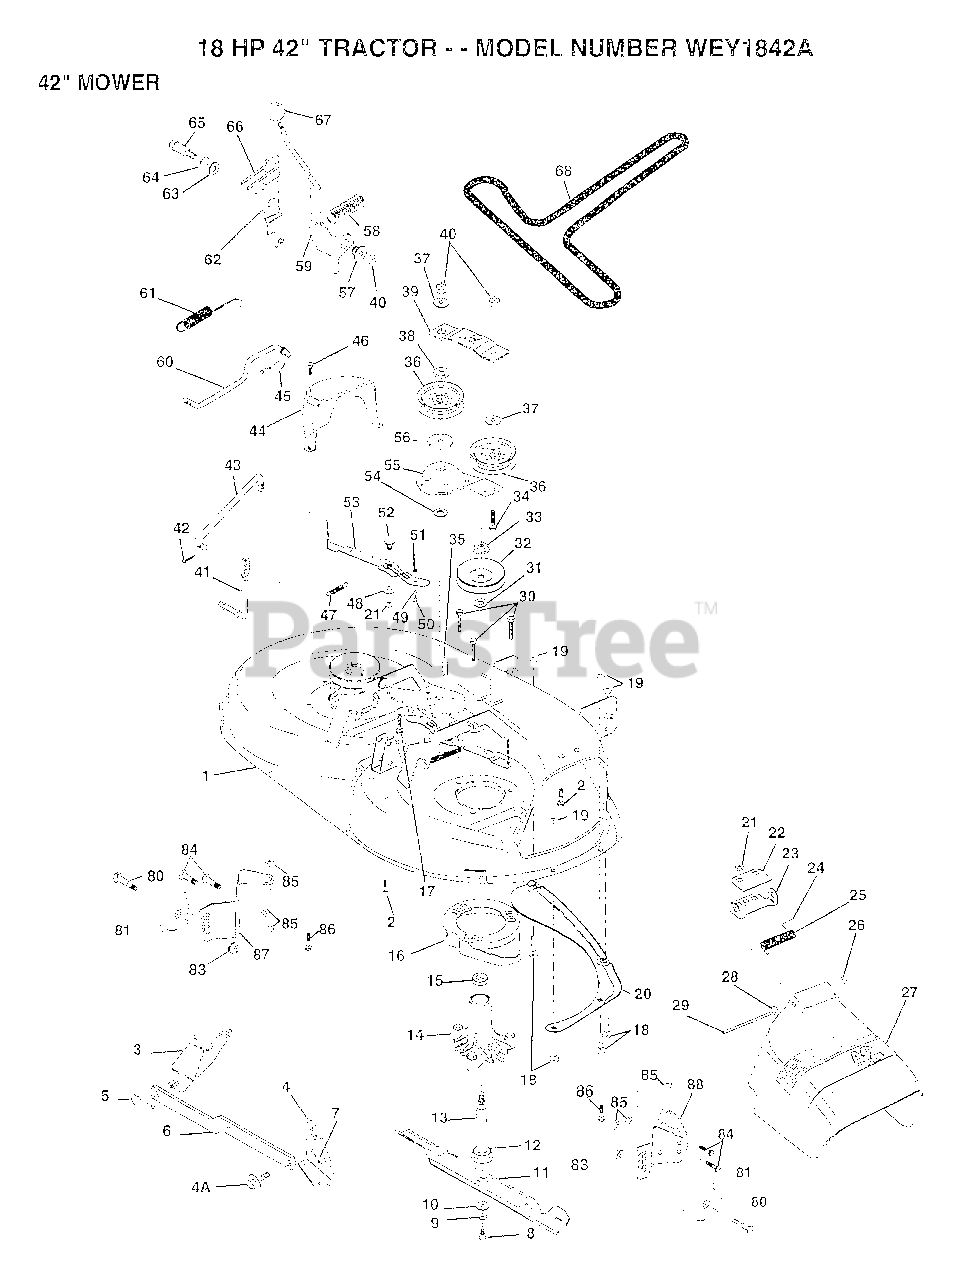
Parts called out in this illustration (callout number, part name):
2	BOLT
3	BRKT ASM SWAY BAR
4	BRKT DECK SW BAR
4A	BOLT SHD 5/16-18
7	NUT
8	BLADE BOLT
10	WASHER BLADE
11	"BLADE.42"" HIPERF"
12	BEARING.BALL
14	HSG ASM MANDREL
15	BEARING
17	BOLT CARRIAGE
18	BOLT
19	NUT
22	STIFFENER BRKT
23	DEFLECTOR BRKT
24	CAP-SLEEVE LT
25	SPRING TORSION
26	NUT PUSH M
27	DEFLECTOR.SHIELD
28	WASHER
29	HINGE ROD
31	WASHER
34	BOLT
35	XMAS TREE FASTNER
36	FLAT IDLER PULLEY
37	WASHER GT
38	RETAINER SPACER
39	IDLER ARM STIFF
41	PIVOT ROD
43	CLUTCH ROD SECOND
45	RETAINER M
46	SCREW.1/4-20X5/8
47	SPRING EXTENSION
48	HARD SMALL WASHER
50	SHOULDER BOLT
51	LOCKNUT
53	BRAKE PAD ARM ASM
54	HARDENED WASHER
55	IDLER ARM
56	SPACER RETAINER
57	BUSHING
59	LEVER.ASM.CLUTCH
60	"ROD, CLUTCH PRIM"
61	RETURN SPRING
62	CLUTCH ARM SECOND
63	WASHER
64	RING
65	SHOULDER BOLT
66	SPRING KEEPER
68	BELT-V.92.4.MWR
80	BOLT M
81	WHEEL.GAGE.BLK.PL
83	NUT
84	BOLT
